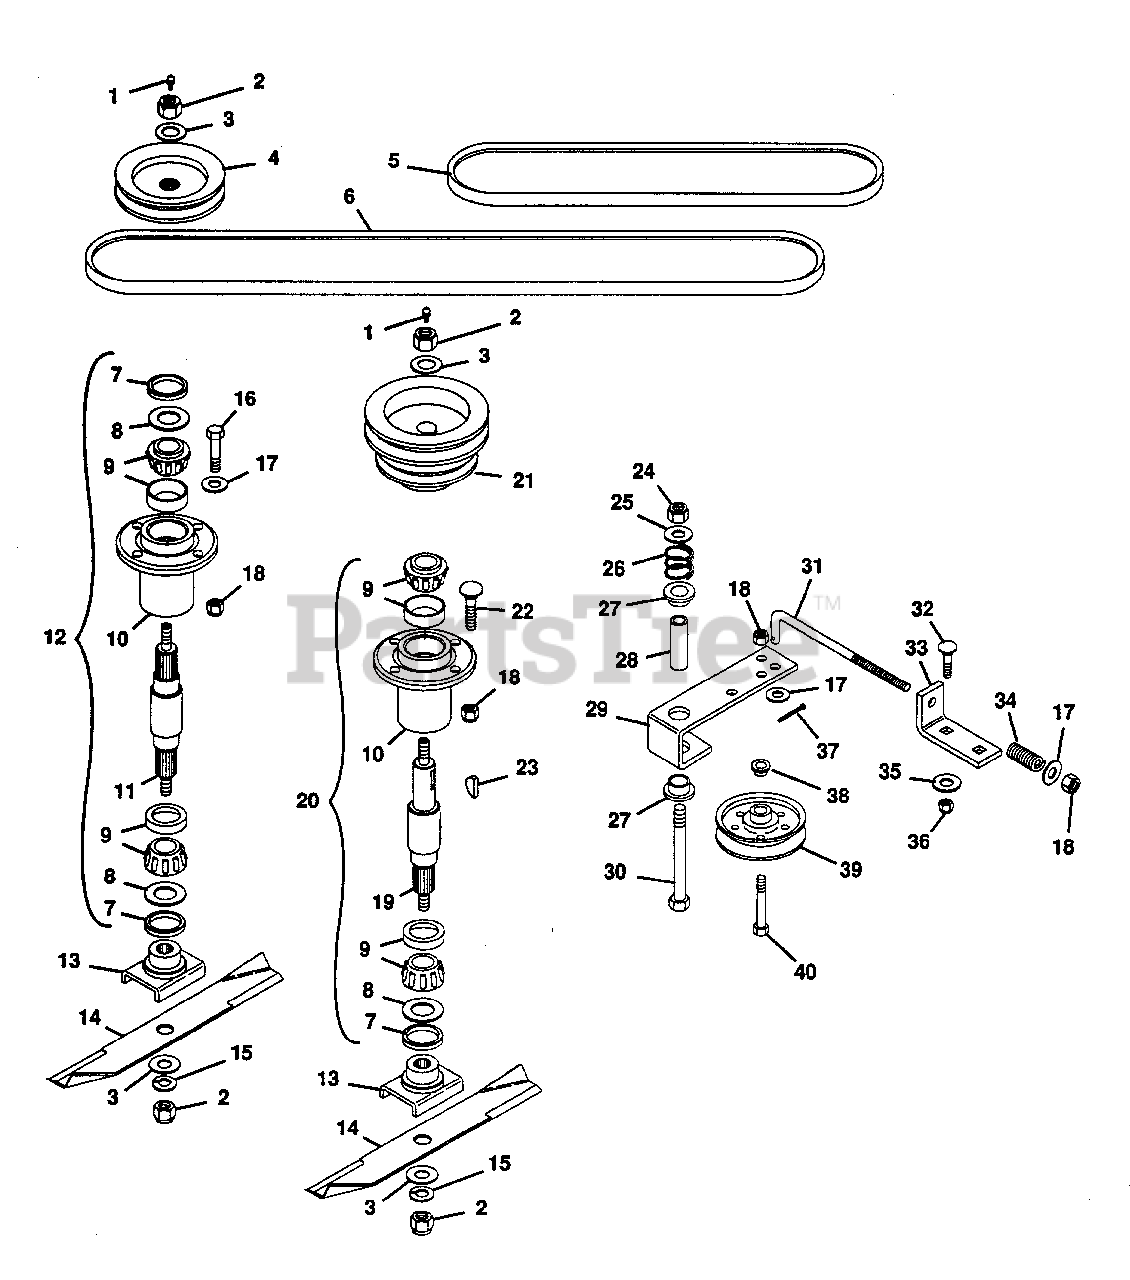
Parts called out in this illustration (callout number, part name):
1	Fitting, Lube 1/8
2	Nut, Lock 5/8-11
3	Wshr, Flat .687x1.312x.122/.146
4	Sheave, Spindle
5	Belt, Mower Drive
6	Belt, Mower
7	Seal, Steel(in 21306)
7	Seal, Steel(in 34605)
8	Washer, Flat .975x1.970x.030(in 21306)
8	Washer, Flat .975x1.970x.030(in 34605)
9	Assembly, Bearing
10	Housing, Bearing
11	Shaft, Spindle
12	Assembly, Spindle
13	Weldment, Blade Cradle
14	Blade
15	Washer, Lock 5/8 SP
16	Bolt, Hex 3/8-16x1.25
17	Washer, Flat .406x.812x.065
18	Nut, Lock 3/8-16
19	Shaft, Spindle
20	Assembly, Spindle
21	Pulley, Drive 40"
22	Bolt, 3/8-16x1.25 Rd Hd Sq Nk
23	Key, Woodruff .250x1.00 HRD #15
24	Nut, Lock 1/2-13
25	Washer, Flat .531x1.250x.100
26	Spring, Comp. 1x.80x36 Lb/In
27	Bush., Flg. .764x1.47x.560 Ny.
28	Bush., St. .560x.750x2.44 Stl.
29	Arm, Idler Pivot
30	Bolt, Hex 1/2-13x3.75
31	Rod, Idler
32	Bolt, Carriage 5/16-18x1.00
33	Bracket, Idler Rod
34	Spring, Comp. 1x.78x338 Lb/In
35	Washer, Flat .344x.688x.065
36	Nut, Lock 5/16-18
37	Pin, Cotter 3/32x1.00
38	Bush., St. .406x.750x.188 Stl.
39	Sheave, Idler
40	Bolt, Hex 3/8-16x2.25
